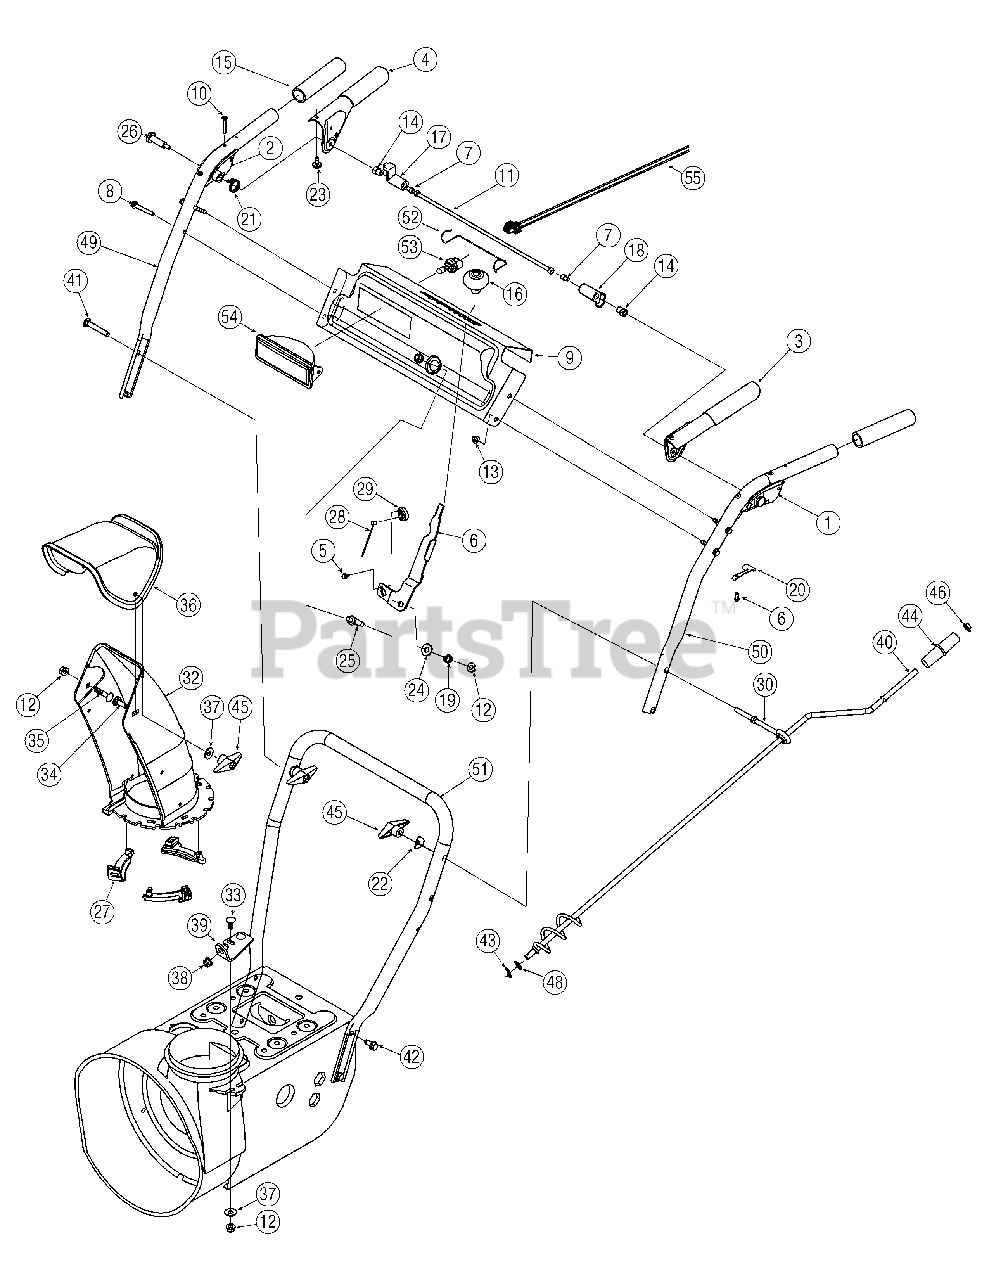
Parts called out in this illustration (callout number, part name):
1	Handle Assembly, Clutch Lock, LH
2	Handle Assembly, Clutch Lock, RH
3	Handle Ass’y, Engagement LH
4	Handle Ass’y, Engagement RH
5	Screw, #10-16, 0.500
6	Screw, #8-16 x .50
7	Screw, 1/4-20, .375
8	Hex Screw, 1/4-20, 1.50,
10	Screw, Machine, #10-24, 1.375
11	Pivot Rod
12	Nut, Flange Lock, 5/16-18, Nylon
13	Nut, Flange Lock, 1/4-20, Nylon
14	Nut, Hex, 1/4-20, Shoulder
15	Grip, 1.0 ID x 5.0
16	Knob, Shift
17	Lock Plate
18	Cam, Clutch Lock
19	Spring, .39 x .60 x .88
20	Spring, Clutch Lock
21	Spring, Torsion, 0.8156 ID x .3038
22	Washer, Saddle, 320 x .93 x .060
23	Bumper, Rubber, .62 OD x .22
24	Washer, Flat, .385 x .870 x .092
25	Bolt, Shoulder, 5/16-18 x 0.905
26	Screw, Shoulder, .43 x 1.3, 1/4 -20
27	Chute, Flange Keeper
28	Cable, Speed Selector
29	Houlder, Cable Barrel, LH
30	Eye Bolt, Chute Crank
33	Bolt, Carriage, 5/16-18, 1.0
34	Bolt, Carriage, 5/16-18, 1.0
35	Bolt, Carriage, 5/16-18, .750
36	Chute, Upper, w/ Label
37	Washer, .349 x .879 x .063
38	Bushing, Plastic, .380
41	Screw, Carriage, 5/16-18, 2.25
42	Screw, 5/16-18, 0.75, Gr5
43	Pin, Cotter, .072 x 1.13
44	Crank Knob, 1.0 Dia. x 3.2 Black
45	Knob Assembly, Wing Nut, 5/16-18
46	Cap, Push, 3/8 Rod
47	Grommet, .44 ID x .94 OD x .5
48	Washer, Flat, .375 x .738 x.063
52	Retainer, Lens
53	Lamp, Halogen, 12V, 27W
54	Lens Assembly, Lamp
55	Wire Harness, Lamp
